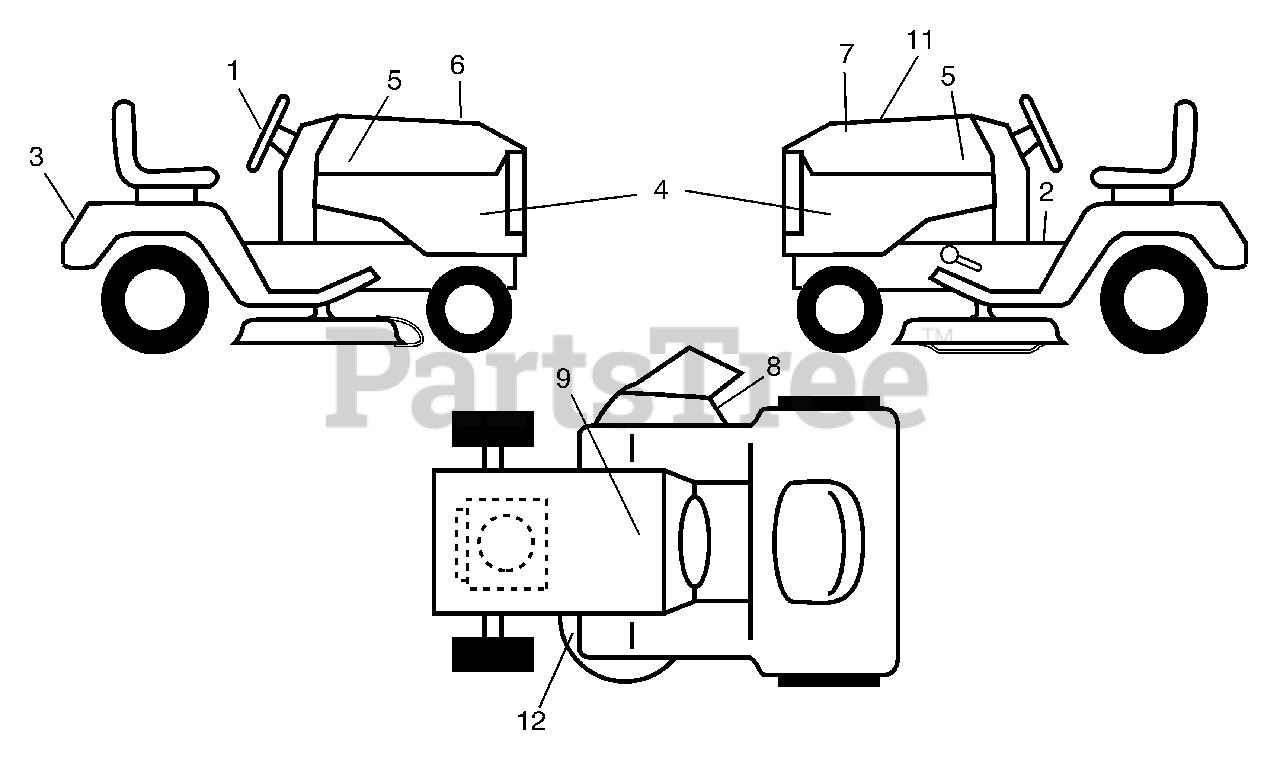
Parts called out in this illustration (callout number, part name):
1	Decal, Steering
2	Decal, Oper/Warn
3	Decal, Fender
4	Decal, Side Panel
5	Decal, Hood Logo
6	Decal, Hood Top Insert
7	Decal, Hood Cust. Resp.
8	Decal, "B"
9	Decal, Battery Dnge/Poi
11	Decal, RPL Koh 20 HP
12	Decal, Mower V-Belt Schematic
